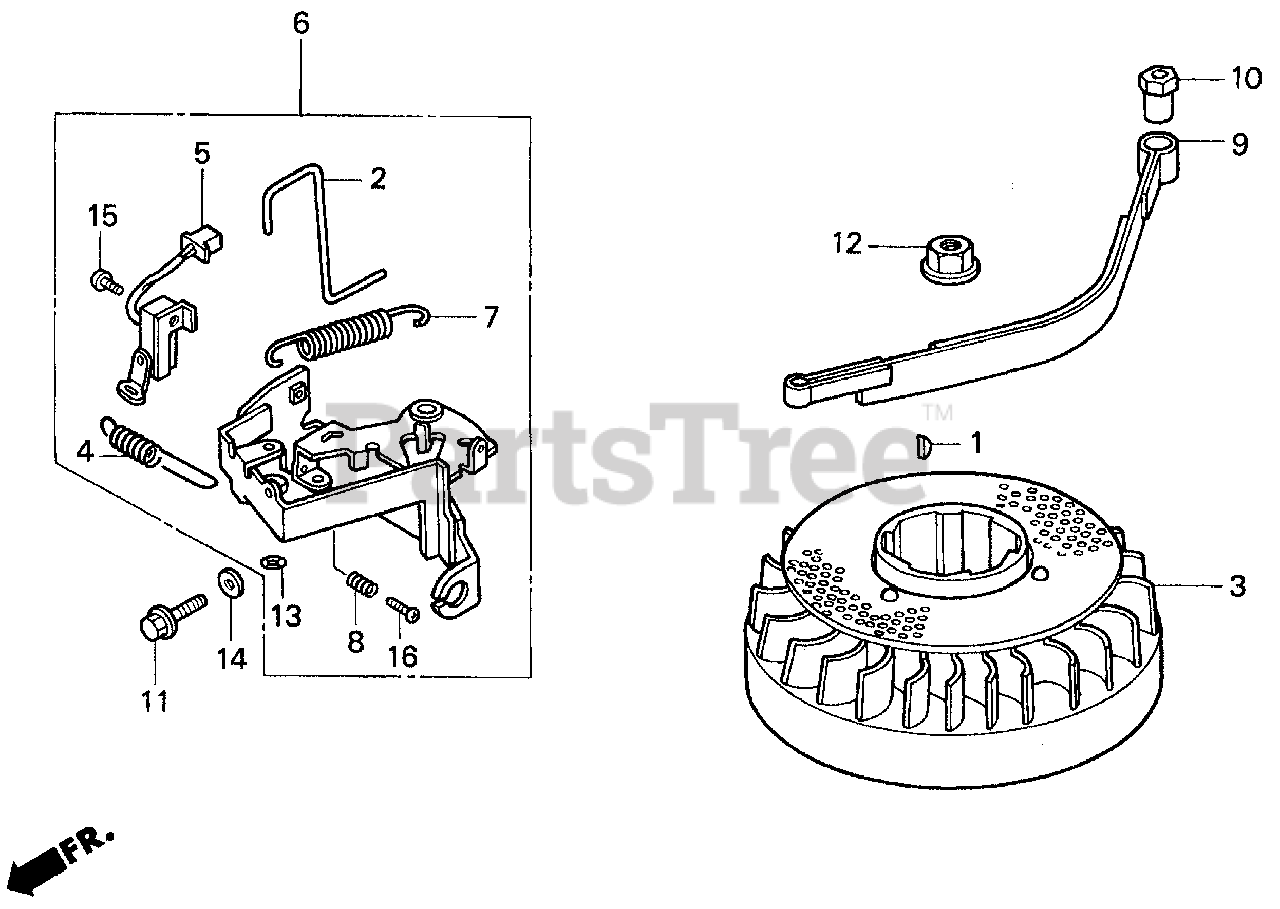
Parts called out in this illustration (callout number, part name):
1	KEY, SPECIAL WOODRUFF (25X18)
3	FLYWHEEL ASSY.
12	NUT, SPECIAL (14MM)
